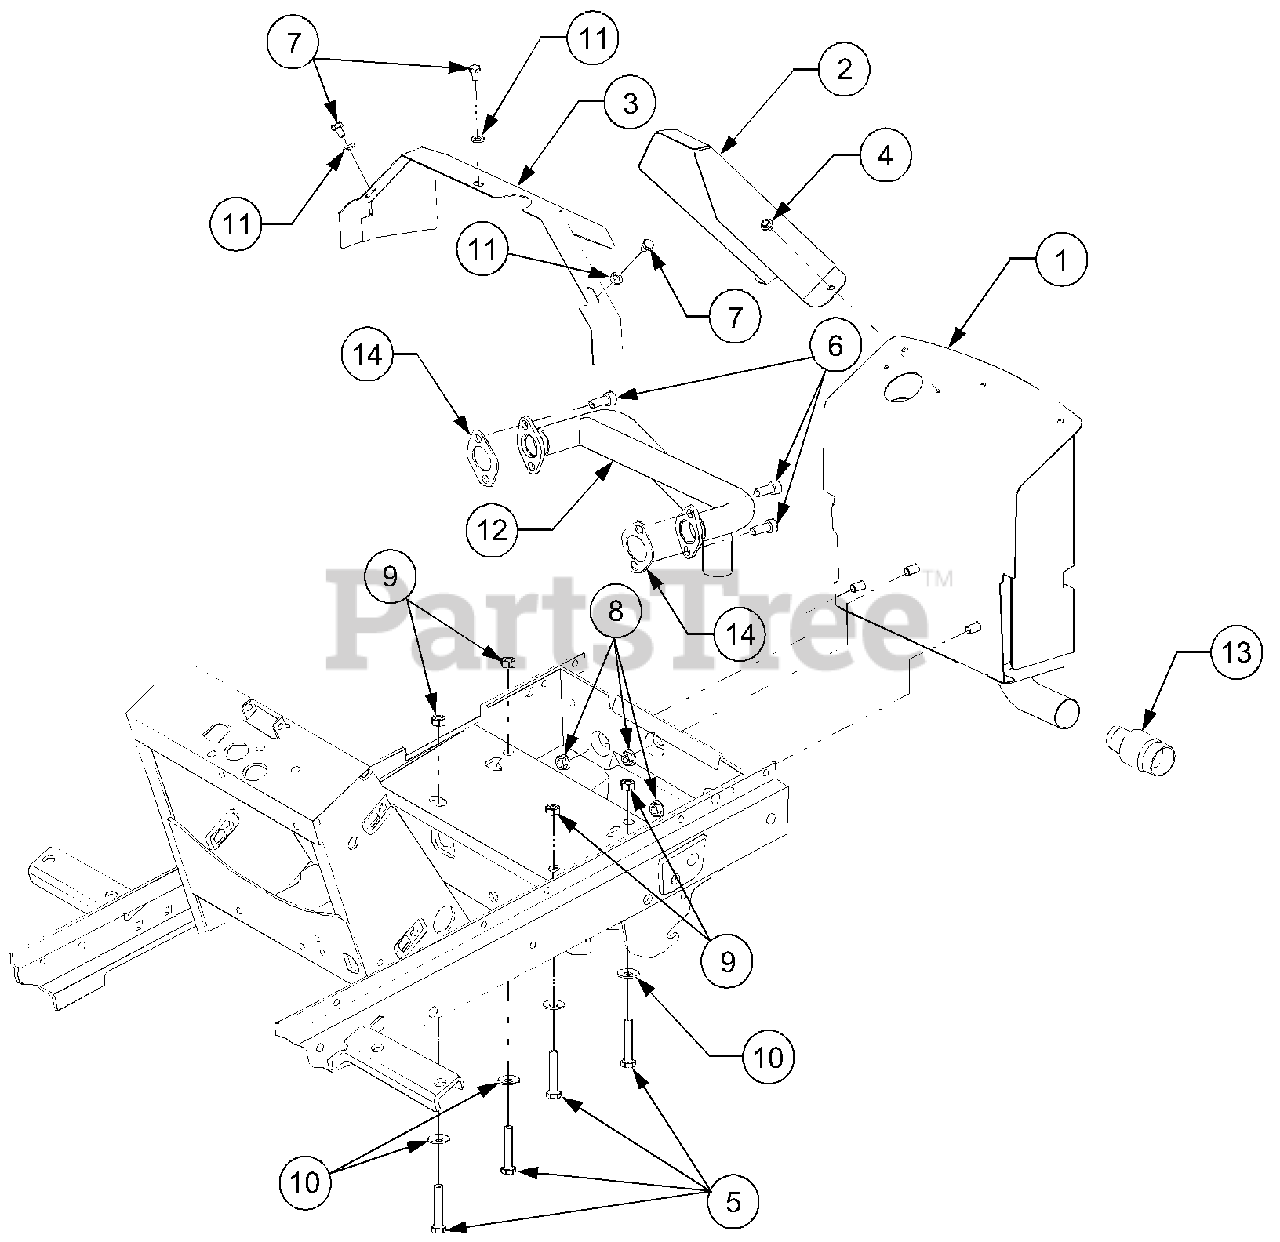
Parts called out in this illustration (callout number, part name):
1	Muffler Assembly
2	Sheild, Muffler Tube
3	Sheild, Engine Heat
4	Screw, Hex Wsh Hd Tap, #10-16 x .38
5	Bolt, Eng Mount, 5/16-18 x 1.75 GR5
6	Screw, Scket Hd Cap, M8-1.25x20mm
7	Screw, Hex Cap, M6-1.0 x 10 GR8.8
8	Nut, Hex Flange Lock, 5/16-18
9	Nut, Hex, 5/16-18 GR5
10	Washer, Bell, .345 x .88 x .060
11	Washer, Flat, .281 x .5 x .063
12	Tube, Exhaust
13	Arrestor, Spark
14	Gasket, Exhaust
